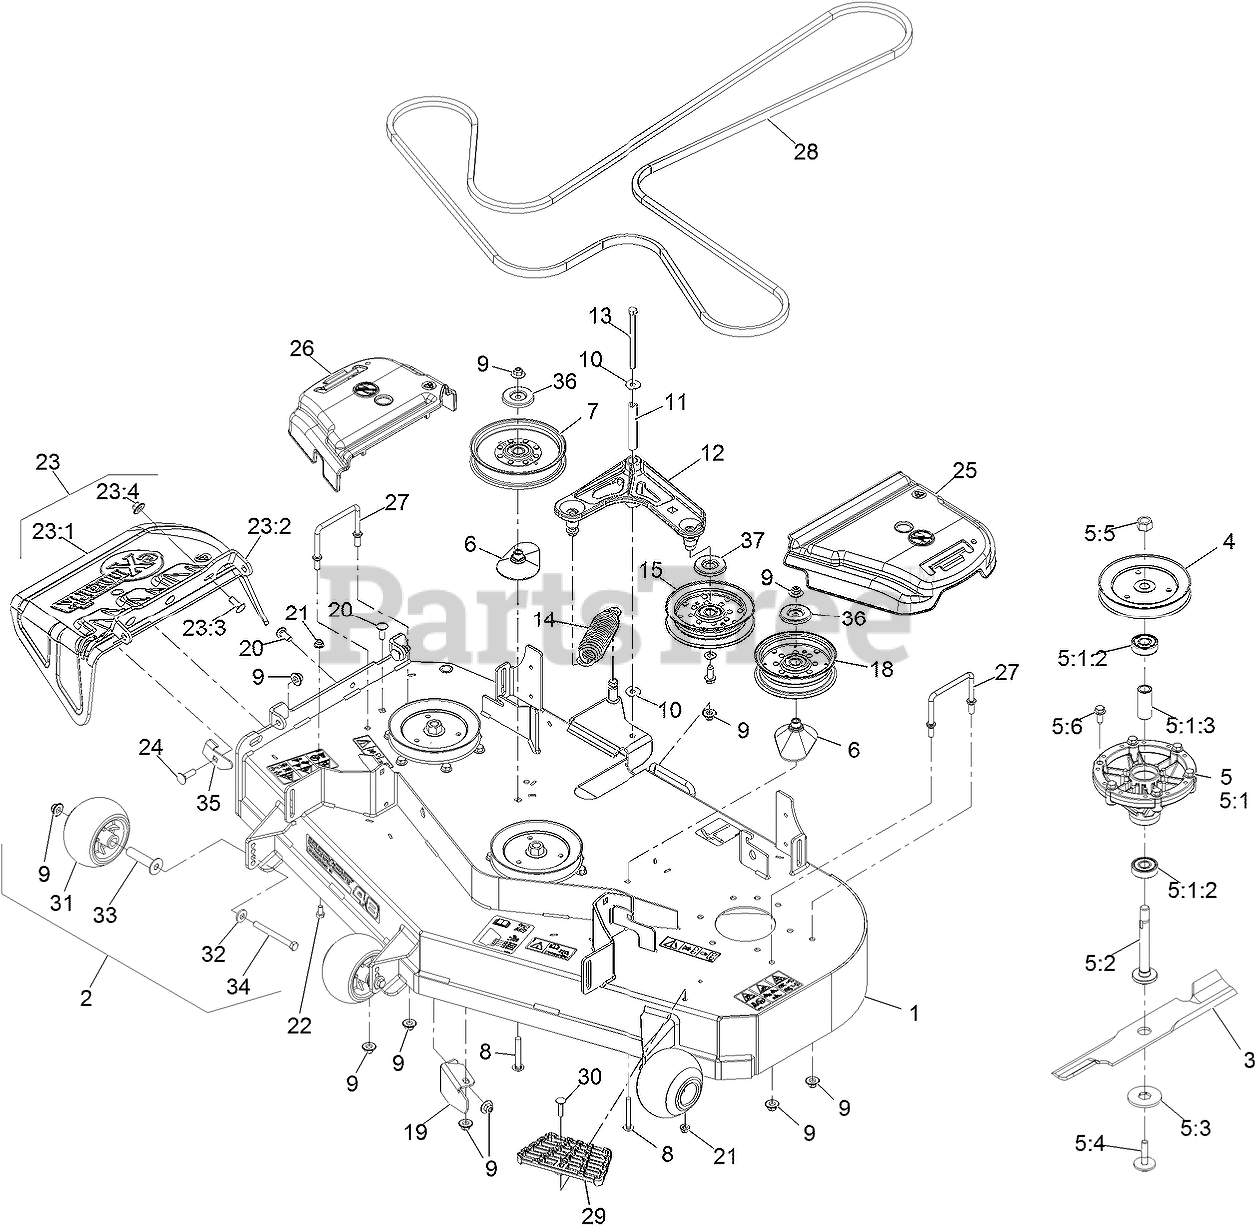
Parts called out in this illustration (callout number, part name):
1	ASM-DECK W/DECALS 483
2	KIT, ANTI-SCALP ROLLER
4	SHEAVE,BLADE DRIVE 5.90
5	ASM, CUTTER HOUSING COMPLETE
5:1	ASM-CUTTER HOUSING
5:1:2	BEARING
5:1:3	SPACER-BEARING
5:2	SPINDLE-HEX PILOT
5:3	WASHER-HEX BLADE DRIVE
5:4	BOLT-BLADE, SEM
5:5	NUT-HEX
5:6	SCREW-FORMING, THREAD
6	SPACER-PULLEY
7	IDLER-PULLEY, FLAT 6.00X1.00
8	SCREW-CARR
9	Nut-Nyloc 3/8-16 Flg
11	BUSHING
12	IDLER ARM ASM
13	SCREW-HH
14	SPRING-EXTENSION
15	IDLER-PULLEY, FLAT
18	IDLER-PULLEY, FLAT 5.00X1
19	BAFFLE,DISCHARGE 483
20	SCREW-CARR
21	NUT-HF, NI
22	SCREW-HH
23	ASM,DISCHARGE CHUTE
23:1	CHUTE,DISCHARGE
23:2	BRACKET,DISCHARGE CHUTE
23:3	SCREW-CARR
23:4	Nut-Nyloc 3/8-16 Flg
24	BOLT-CARR
25	COVER-BELT, LH
26	COVER-BELT, RH
27	WIREFORM-COVER
29	STEP-DECK
30	Bolt-Carriage 5/16-18 X 1 1/4
31	ROLLER-SCALP, ANTI
32	WASHER-BELLEVILLE
33	AXLE, ROLLER
34	SCREW-HH 3/8-16 X 3 3/4 GR 8
35	STOP-DISCHARGE CHUTE
36	SHIELD-DUST
37	SHIELD-GUARD, DUST
